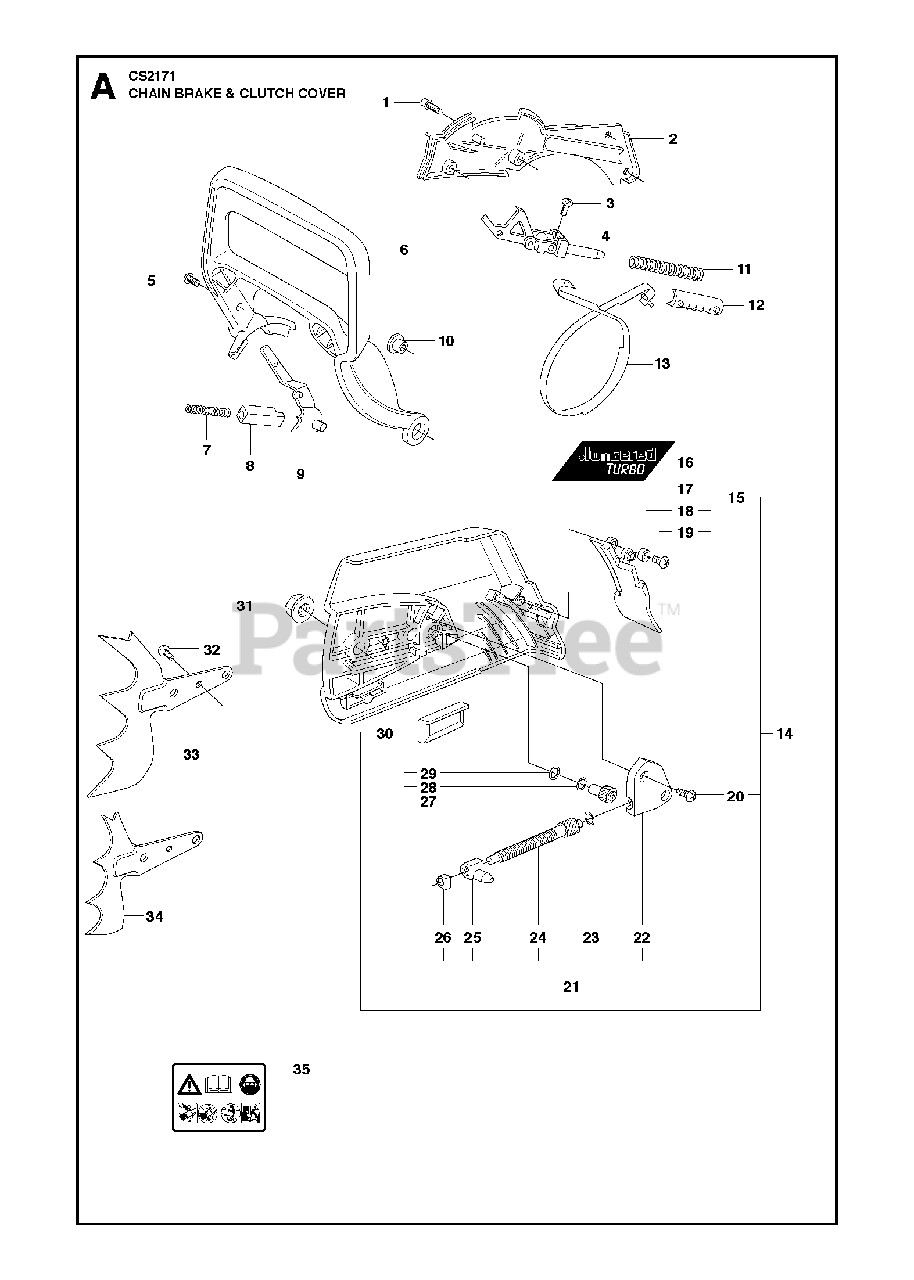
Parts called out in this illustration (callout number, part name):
1	SCREW
4	KNEE LINK
6	HAND GUARD
7	LOCK SPRING
9	BRAKE LEVER
11	BRAKE SPRING
13	BRAKE BAND
14	CLUTCH COVER
15	CLUTCH COVER
16	DECAL
17	PROTECTOR
18	WASHER
19	SCREW
20	SCREW
21	KIT-CHAIN TENSIONER
22	COVER
23	WASHER
24	WORM SCREW / ADJUSTER
25	COUPLING
26	SLEEVE
27	SCREW
28	WASHER
29	O-RING
30	CHAIN GUIDE
31	NUT M8 FLANGE
33	FELLING DOG
34	FELLING DOG
